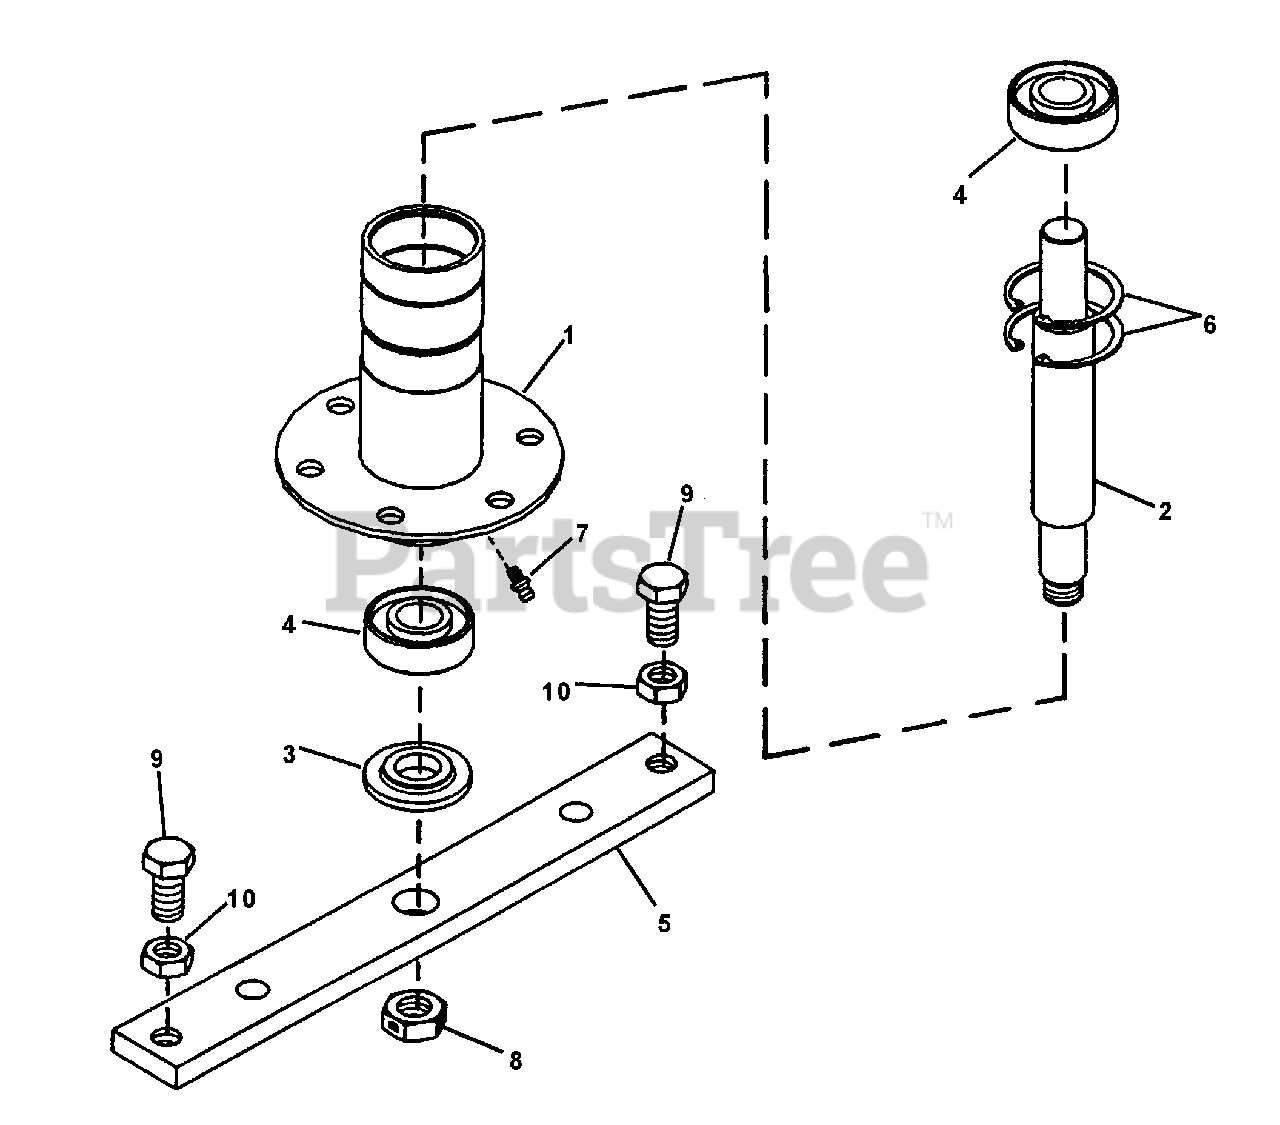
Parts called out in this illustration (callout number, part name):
1	HOUSING, Spindle
2	SPINDLE, Shaft (7.54" Long)
3	WASHER
4	BEARING, Spindle
5	HOLDER, Blade
6	RING, 1-3/4" External Retaining
7	FITTING, Lube (Press fit for .187 hole-no ball)
8	NUT, 5/8-18 Hex Center Lock Jam
9	SCREW, 1/2-20 x 1" Hex Head Cap
10	NUT, 1/2-20 Hex Jam
